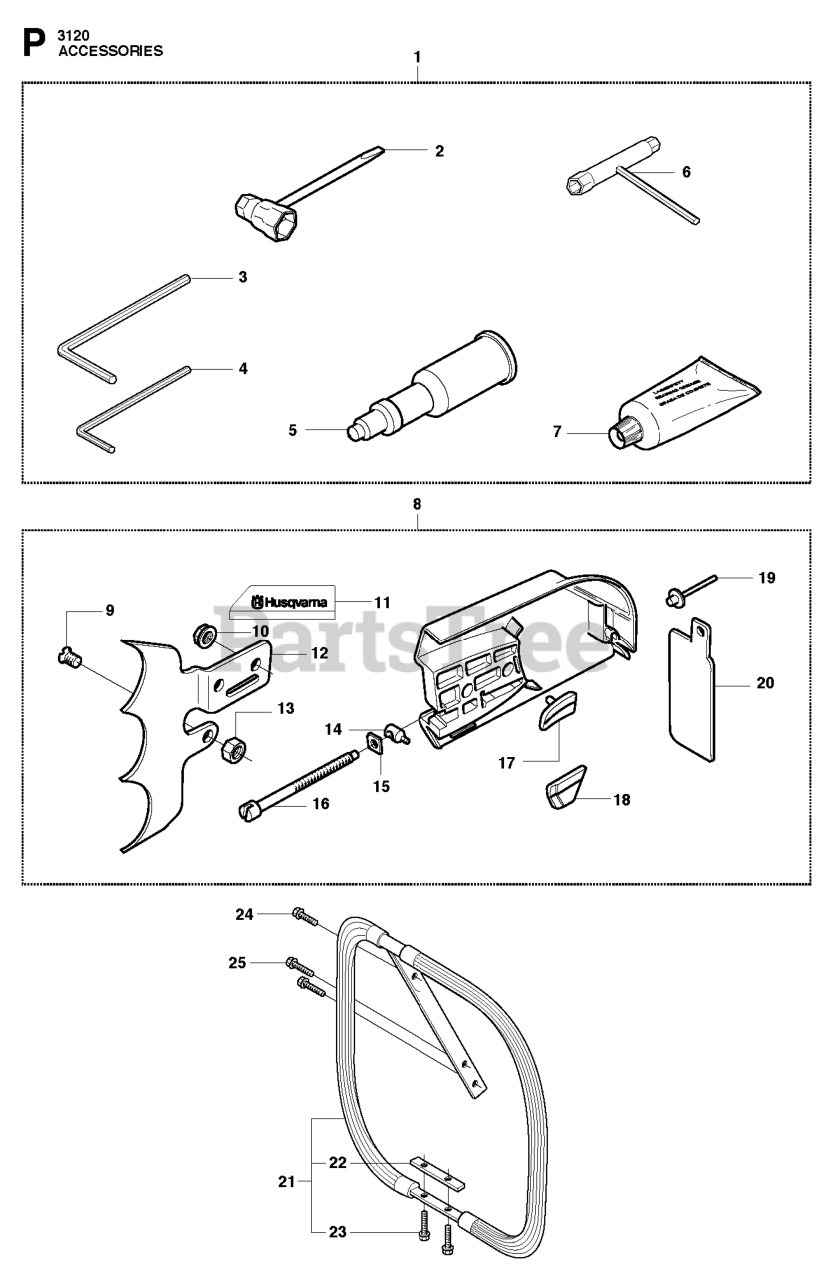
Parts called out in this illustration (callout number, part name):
2	COMBI TOOL
3	L-SPANNER
4	L-SPANNER
5	Grease Gun
6	COMB.TOOL 8-10-14
7	GREASE
8	CLUTCH CVR 3120K ONLY NO CHNBR
9	SCREW MF6S 6X14
10	NUT M8 FLANGE
12	FELLING DOG
14	PULLER UNIT
17	CHAIN GUIDE
18	CHAIN GUIDE
20	DUST GUARD
23	SCREW MC6S 6X30
24	SCREW
